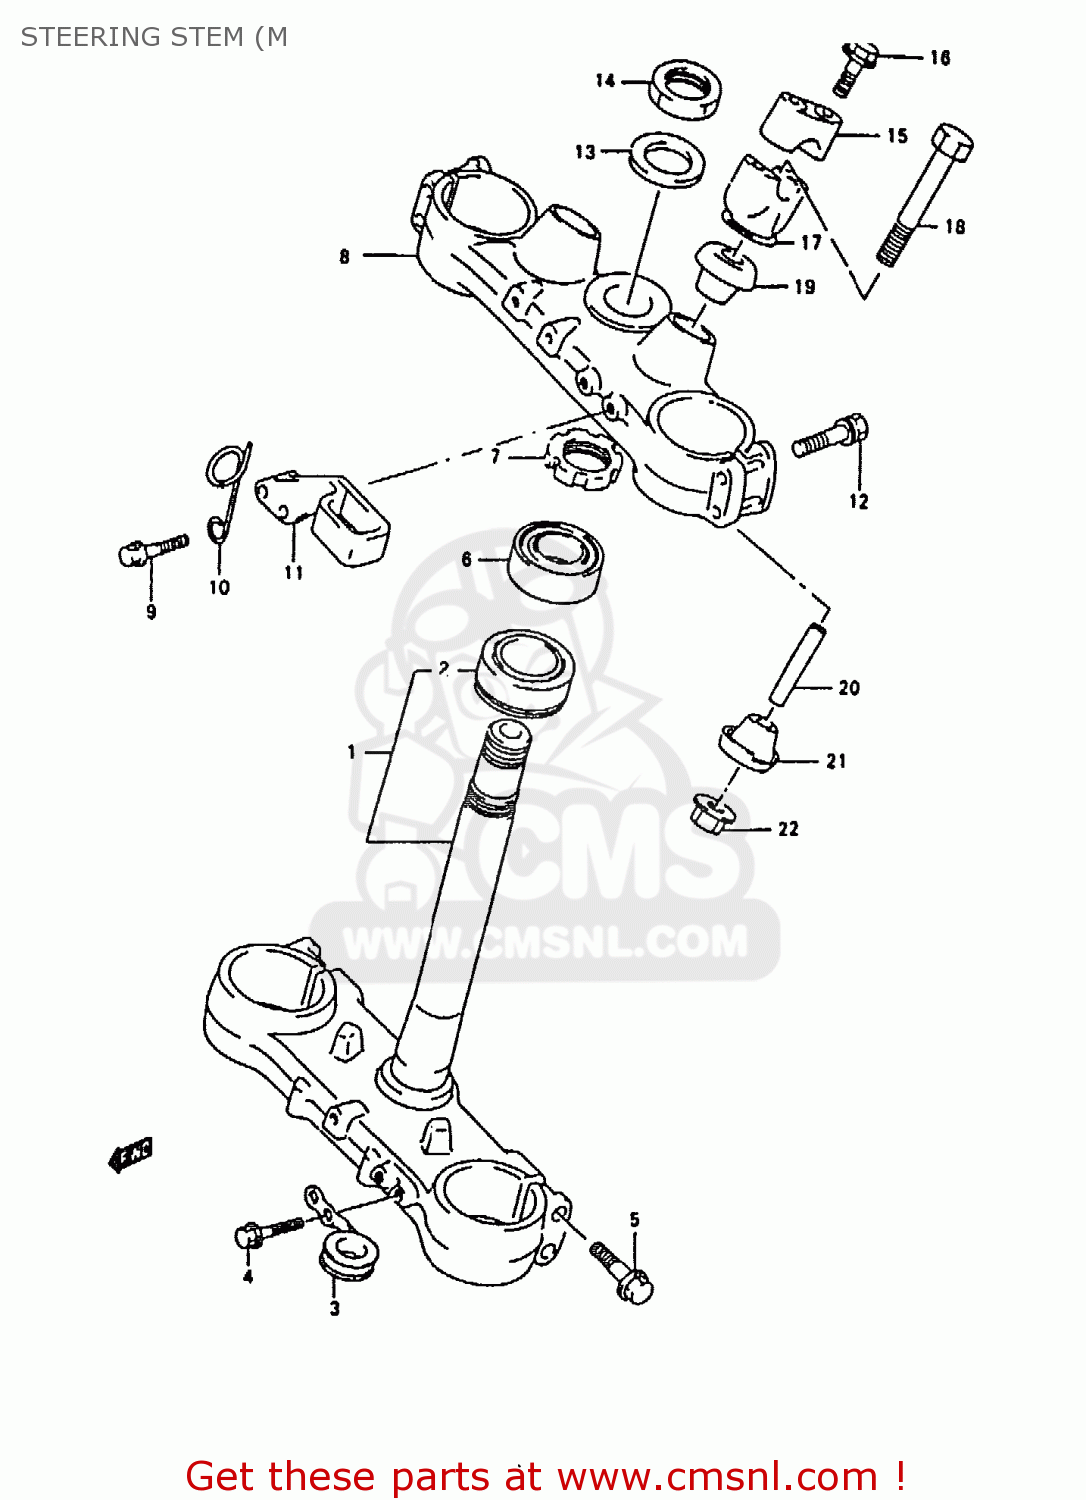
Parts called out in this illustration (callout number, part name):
1	STEM,STEERING
2	BEARING(30X52X16)
3	GUIDE,CABLE LWR
4	BOLT,PROTECTOR(6X10)
5	BOLT
6	BEARING(30X52X16)
7	NUT,STEERING
8	HEAD,STEERING STEM
9	BOLT,GUIDE
10	GUIDE,CLUTCH CABLE
11	GUIDE,HOSE
12	BOLT
13	WASHER,STEM HEAD
14	NUT,STEM HEAD
15	HOLDER,HANDLEBAR
16	BOLT,HANDLE HOLDER(8X35)
17	HOLDER,HANDLE UNDER
18	BOLT,HANDLE HOLDER(10X70)
19	CUSHION,RUBBER UPR
20	SPACER
21	CUSHION,RUBBER UNDER
22	NUT
23	NUT
24	NUT
25	NUT
26	COTTER PIN
